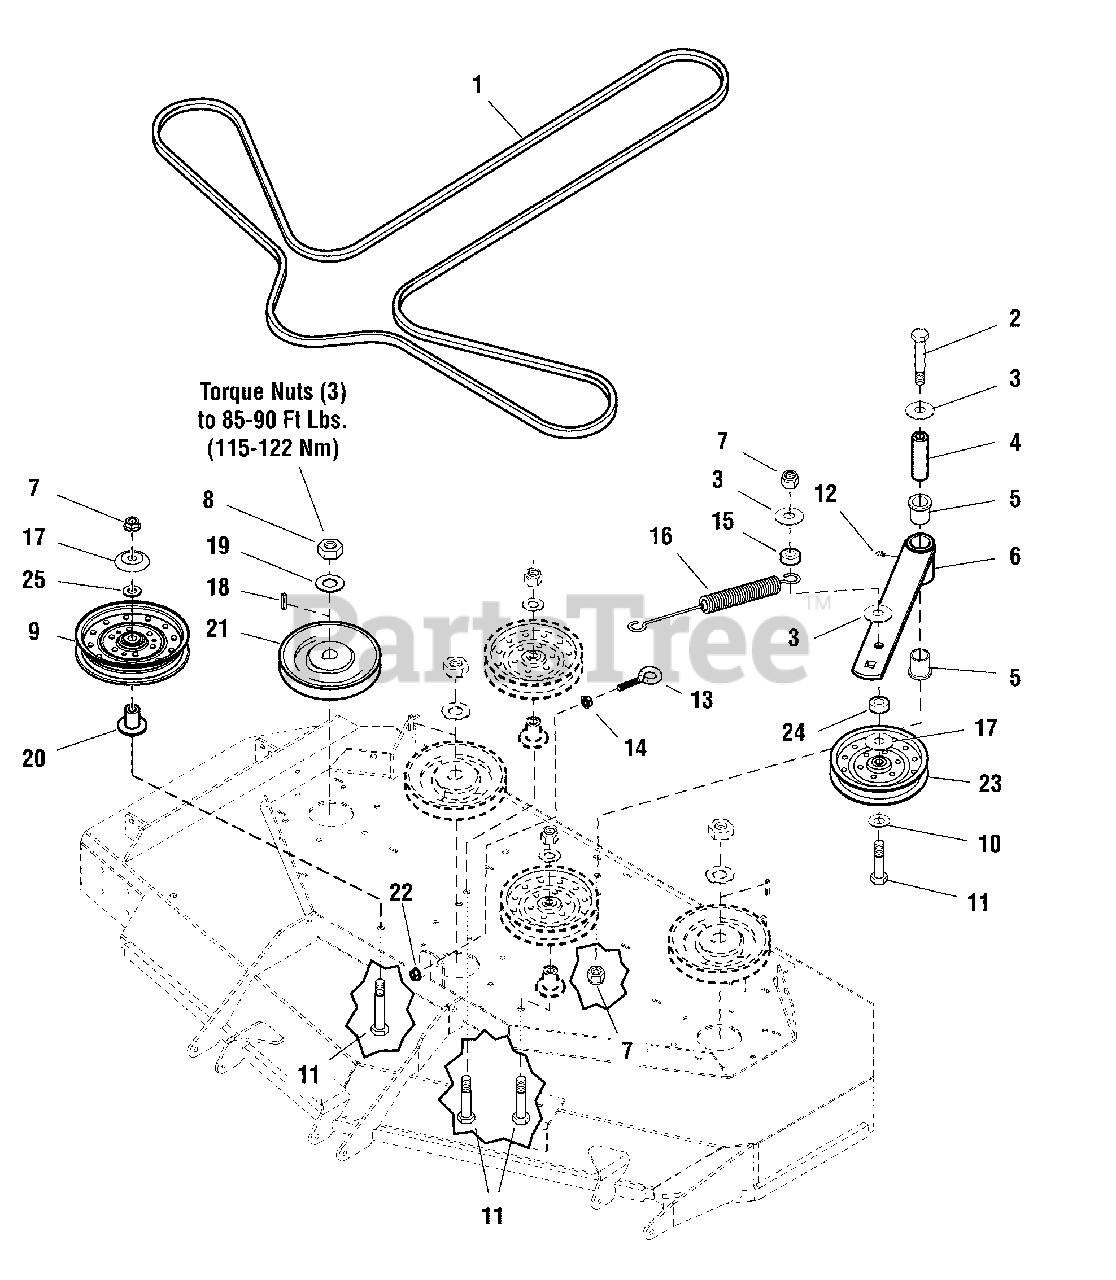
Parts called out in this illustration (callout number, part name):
1	BELT, 5V, 175.90EL, LG ARAMID, WRPD, RC
2	BOLT, 1/2-13 X 4-1/2" GD5
3	WASHER, 1/2" USS
4	SPACER, .52 X 1.00 X 3.50
5	BUSHING, FLANGE
6	IDLER ARM ASSM
7	NUT, 1/2-13 HEX NYLOCK FLANGE
8	NUT, 3/4-16 HEX
9	*PULLEY, FLAT IDLER, 6-3/4"
10	WASHER, 1/2" GD9 YZ
11	BOLT, 1/2-13 X 3" GD5
12	GREASE FITTING, 1/4-28 STRAIGHT
13	EYE BOLT, 3/8-16 X 6, 3.0 THRD, 1 EYE
14	NUT, 3/8-16 HEX JAM
15	SPACER, .52 X 1.00 X .38
16	SPRING, EXTENSION, SWIVEL END
17	SHIELD, PULLEY BEARING
18	KEY, 1/4" SQ. X 1-1/4
19	WASHER, 3/4" BELLEVILLE
20	WELD, MOUNT, IDLER
21	PULLEY, 6.5 EOD X 25MM, SPLIT
22	NUT, 3/8-16 HEX NYLOC
24	SPACER, .52 X 1.00 X .56, CZ
25	WASHER, 1/2 SAE
